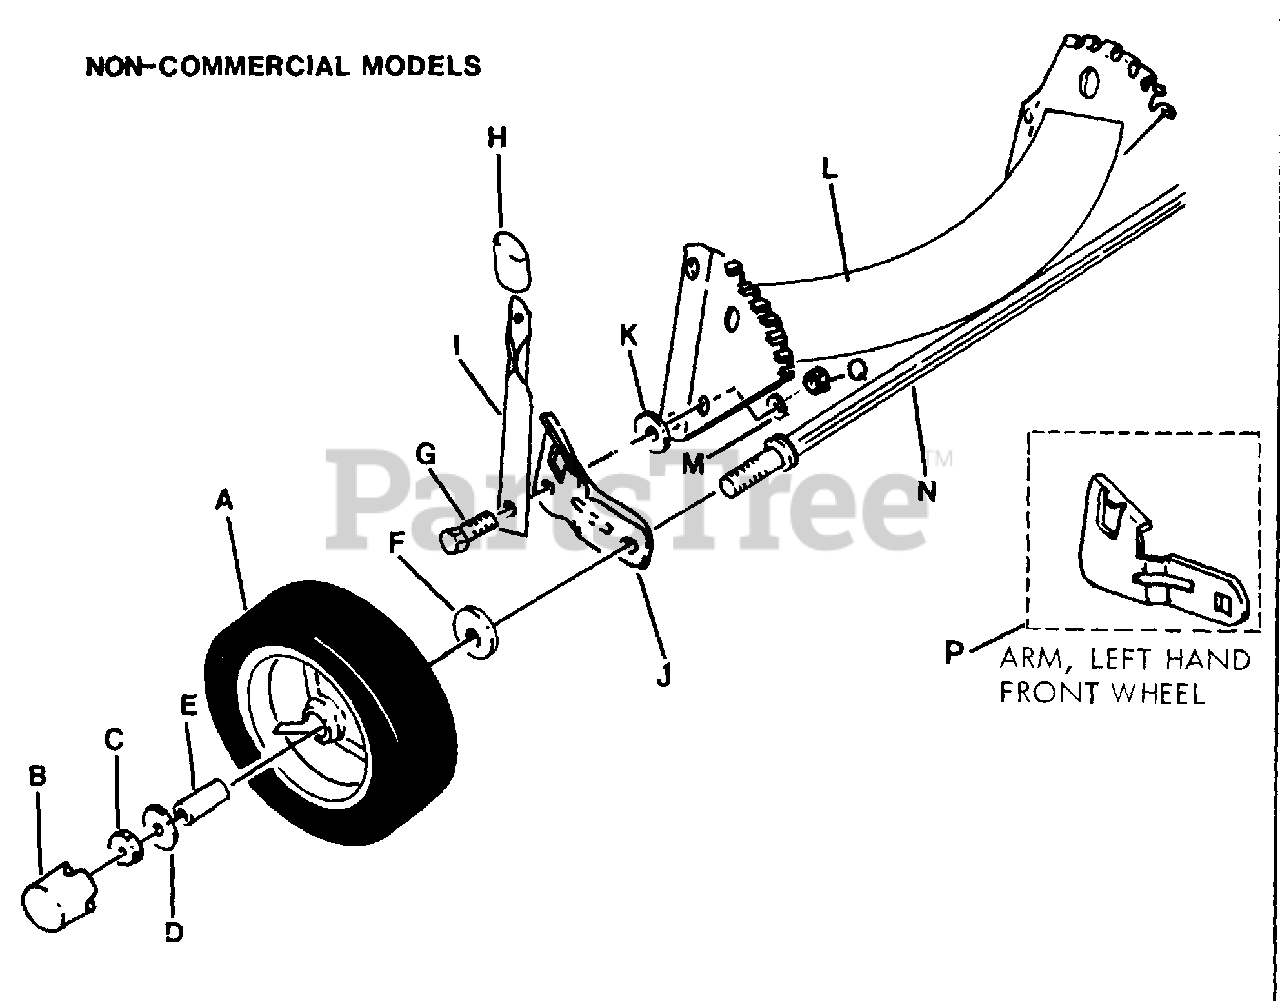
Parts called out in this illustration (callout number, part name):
A	WHEEL, FRONT 7 x 1.50
B	CAP, HUB - 21400 & 21400P
C	NUT, 7/16F HEX LOCK
D	WASHER, SPRING
E	BUSHING, AXLE
F	WASHER, STEEL
G	SCREW, SHOULDER 5/16-18 x 1"
H	GRIP, HEIGHT LATCH
J	ARM, RIGHT HAND FRONT WHEEL
K	RETAINER, BOLT
L	BRACKET, FRONT WHEEL -- STRUCTURE
M	LOCKWASHER, 5/16 INTERNAL TOOTH
N	AXLE, FRONT WHEEL
P	ARM, LEFT HAND FRONT WHEEL
Q	NUT, 5/16-18 HEX
